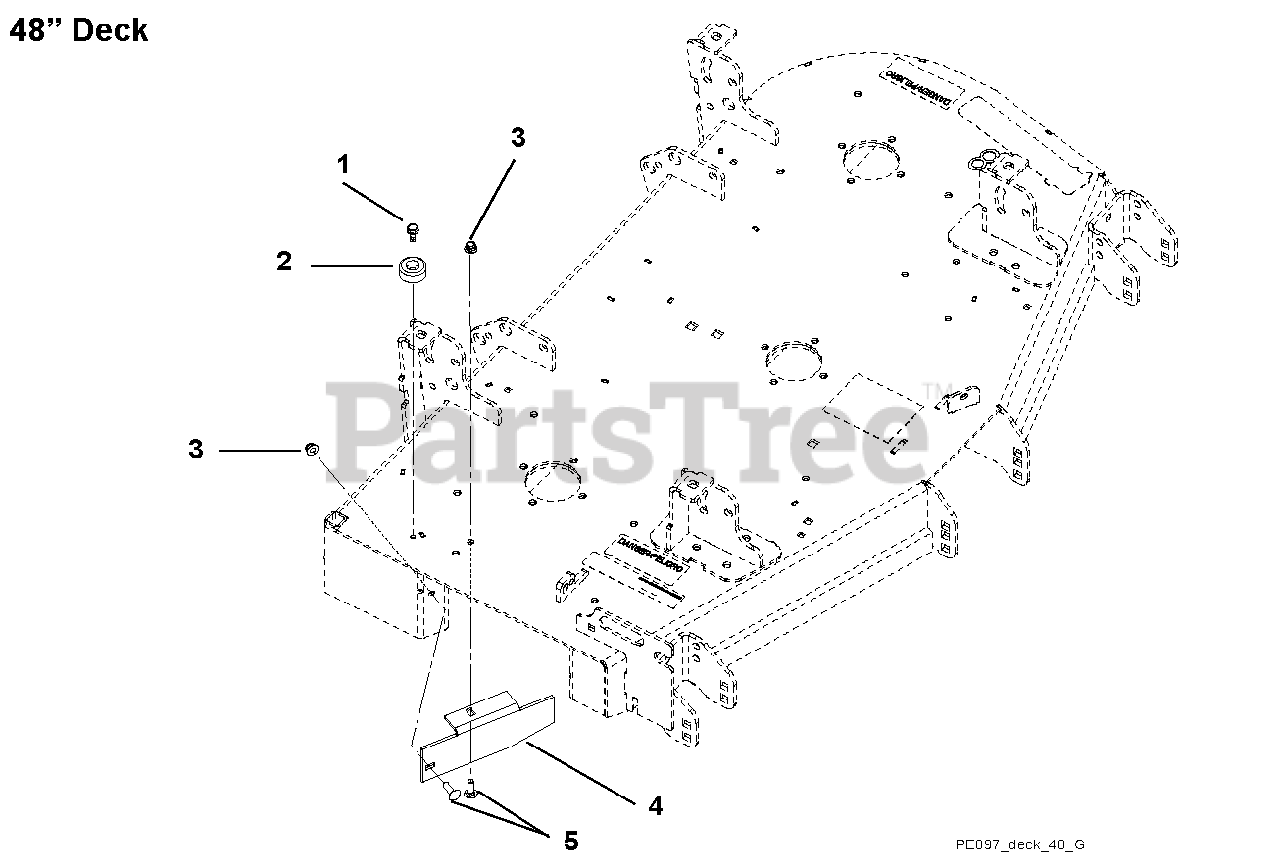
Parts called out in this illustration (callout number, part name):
1	Screw, Tapping .31-18 x .75 Hex Washer Head
2	Bumper, Recessed 1.50 x .63 w/.31 Thru Hole
3	Nut, Locking Nyloc Flange .31-18
4	Discharge Baffle
5	Bolt, Round Head Square Neck .31-18 x 1.00
